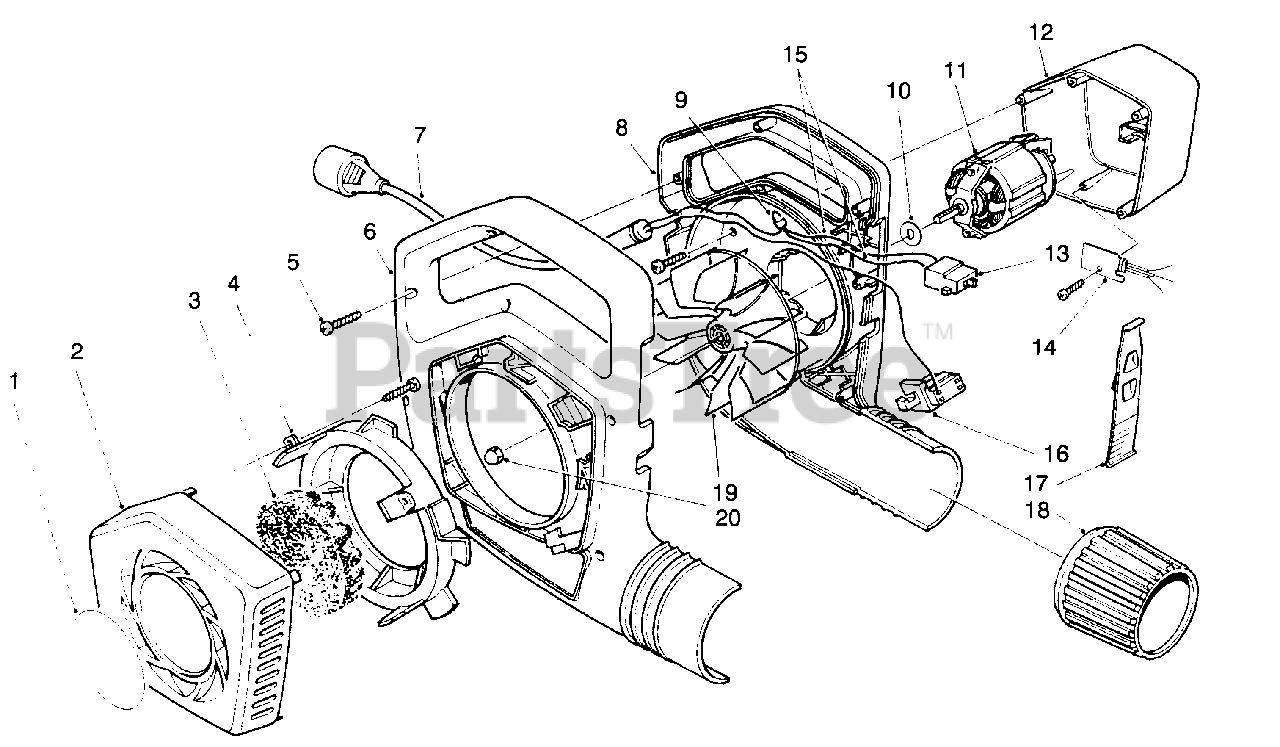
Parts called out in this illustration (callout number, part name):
1	Decal-Cover
2	Cover-Intake
3	Foam-Center
4	Ring-Coupling
5	Screw-Self Tapping
6	Housing-Blower, R.H.
7	Cord-Power Supply
8	Housing-Blower, L.H.
9	Connector-Wire
10	Washer-Impeller
11	Motor-Blower
12	Cover-Motor
13	Switch-2 Speed
14	Diode Assembly
16	Switch-Interlock
17	Switch-Cam, 2 Speed
18	Collar-Output
19	Impeller
20	Nut-Cap, Locking
